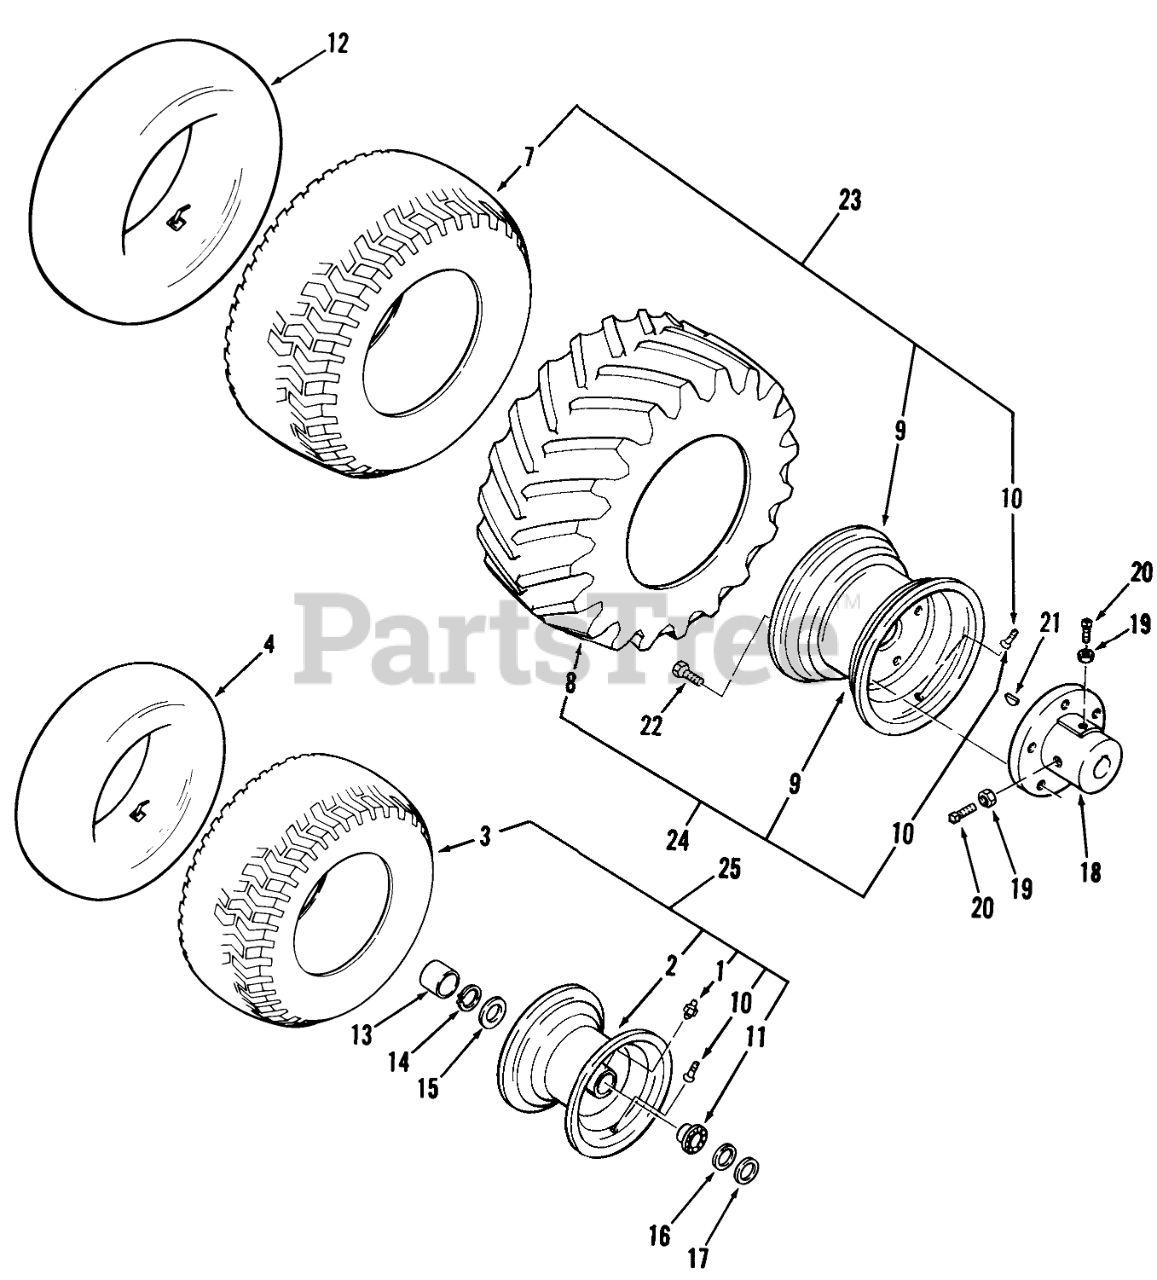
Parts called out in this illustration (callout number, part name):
1	Zerk
2	Front Wheel (Includes Item 1)
3	TIRE TURF SAVER 16X6.50-8
4	TUBE-INNER
7	TIRE 9.50 X 12
7	Tire
8	Tire-Cleat, Rear
9	Wheel
10	VALVE
11	Ball Bearing
12	TUBE-INNER
13	HUB CAP
13	HUB CAP-FLAT BLACK
14	Snap Ring
15	WASHER-WHEEL
16	WASHER
17	WASHER-SHIM
18	Hub Rear
19	Nut
20	Screw-Set
21	KEY-WOODRUFF
22	Lug Nut
23	Engine
23	Wheel and Tire
24	Right Rear Wheel and Tire Assy-Cleat
24	Left Rear Wheel and Tire Assy-Cleat
25	ASSY-WHEEL & TIRE
